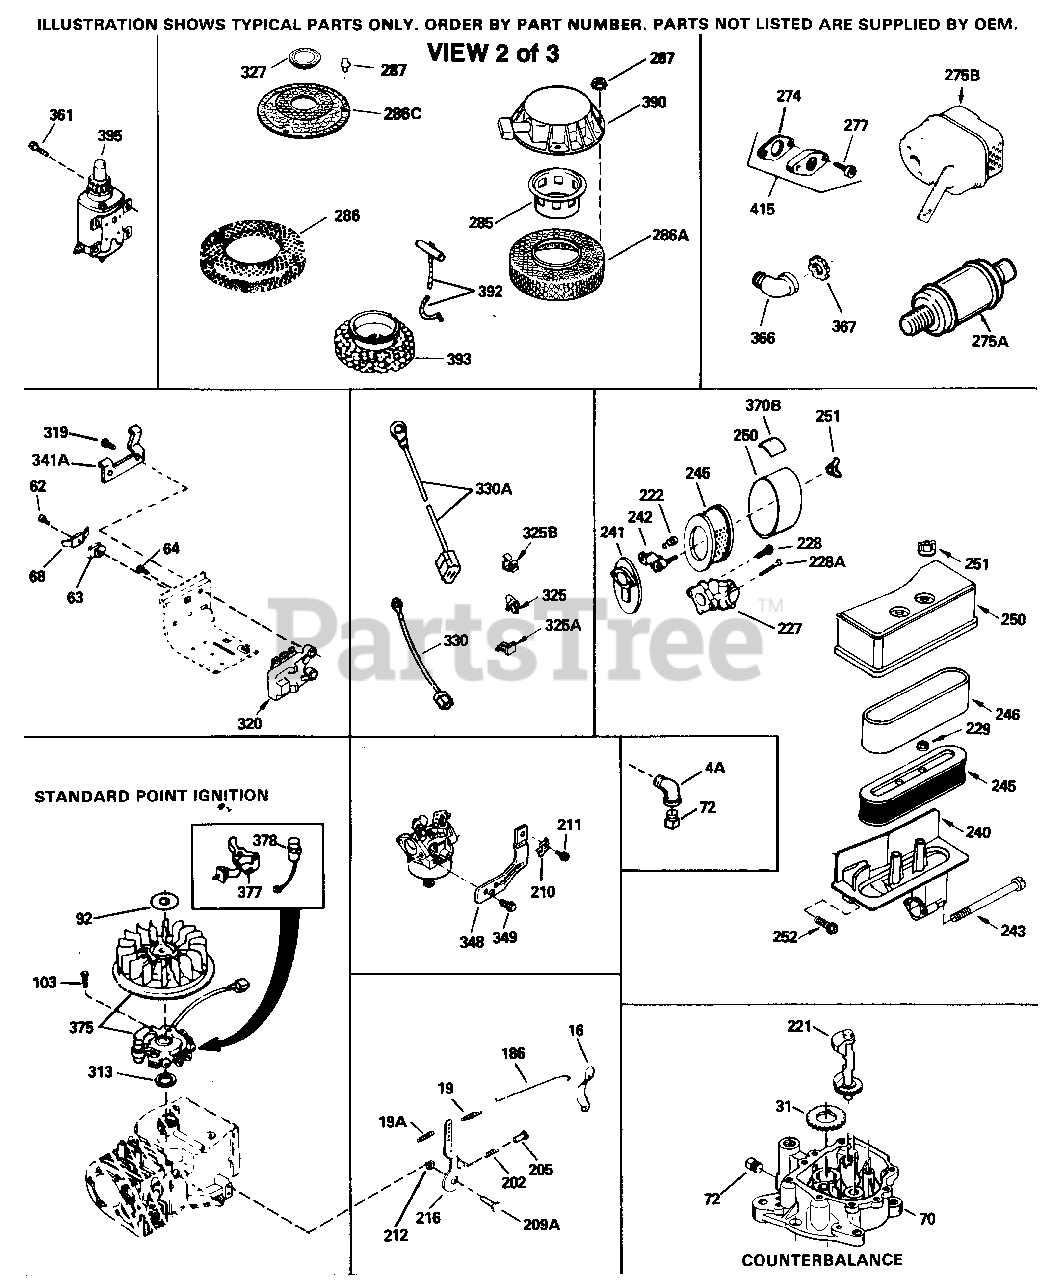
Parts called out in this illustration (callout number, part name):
16	Lever, Governor
19	Spring, Extension
19A	Spring, Extension
64	Screw, T-30, 1/4-20 x 1/2"
70	Flange Ass'y. (Incl. 72, 75, 80 & 81)
72	Plug, Pipe
92	Washer, Flat
92	Washer, Belleville
103	Screw, 1/4-20 x 5/8"
186	Link, Governor-to-throttle
202	Spring, Compression
205	Screw, 5-40 x 7/16"
210	Conduit Clip
211	Screw, 10-32 x 3/8"
240	Body, Air cleaner
243	Screw, 10-32 x 1-17/32"
274	* Exhaust Gasket (use as required)
277	Screw, 5/16-18 x 3/4" .)
277	Screw, 5/16-18 x 3-3/16" Use As Req.
277	Screw, 5/16-18 x 4-3/16" Use As Req.
286	Hub & Screen Assy., Starter
313	Gasket, Stator
327	Plug, Screen
375	Magneto NOTE: The following completem agnetos are not available as an assem bly. The magneto numbers are shown fo r reference purposes only. Order com ponent parts individually, as shown i n parts breakdown. (Refer to Division 5, Section B, page 28
377	Breaker Points (also available in Pac kaged Part #740037B)
378	Condenser (also available in Packaged Part #740037B)
415	Exh.Adapter Kit (Incl. 274 & 277) As req.
